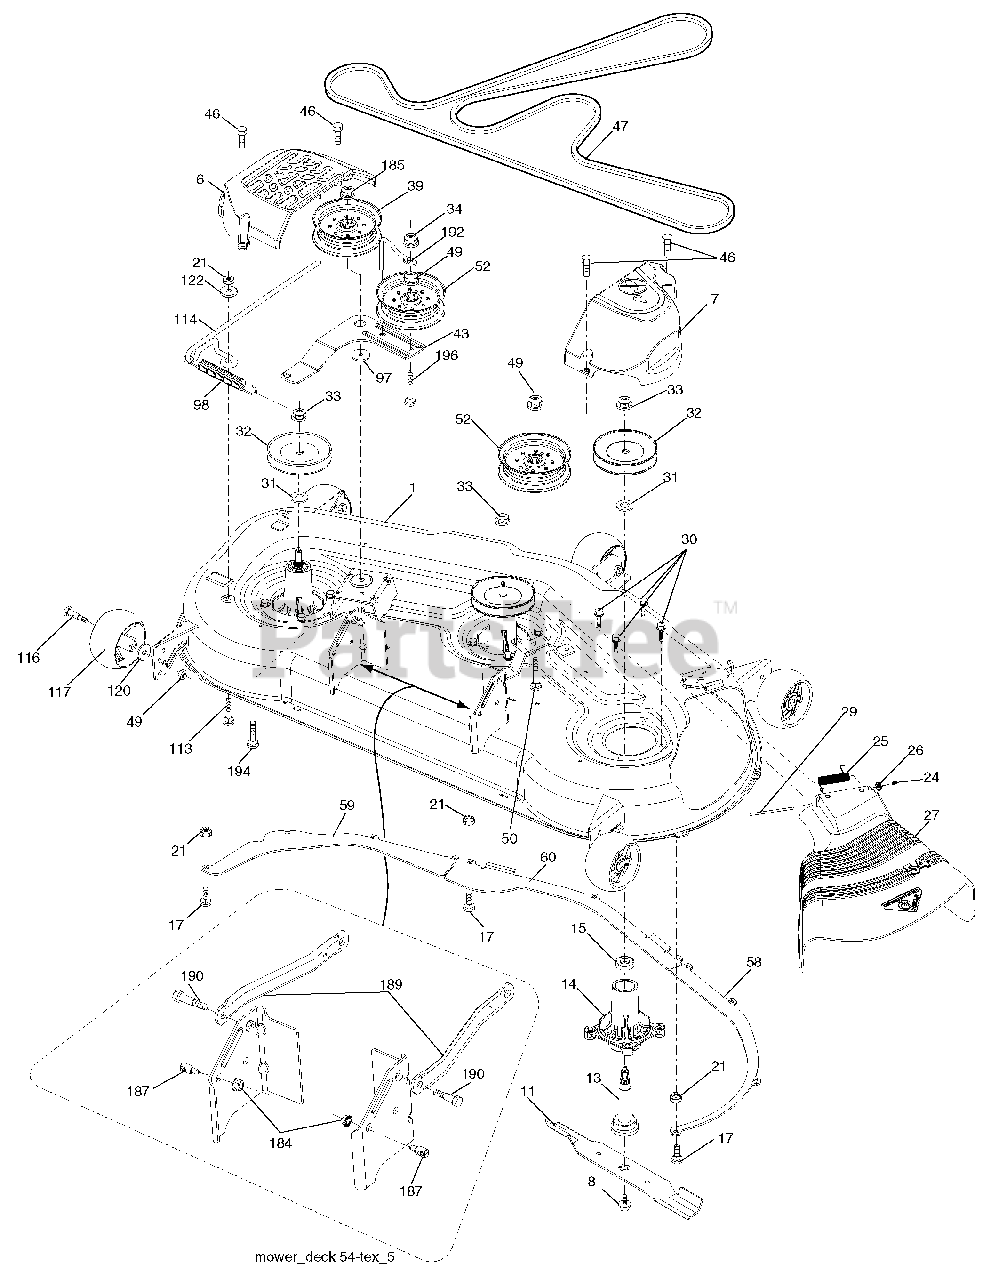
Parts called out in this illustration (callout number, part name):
1	Deck Weldment Mower
6	Cover Mandrel LH
7	Cover Mandrel RH
8	Bolt 7/16 Asm. Blade
8	Blade Mulching
11	Blade Bagging
13	Shaft Asm. w/Lower Bearing
14	Housing, Mandrel
15	Bearing, Ball, Mandrel
17	Bolt Carr. 5/16-18 x 5/8
21	Nut, Crownlock 5/16-18 unc
24	Cap Sleeve
25	Spring, Torsion
26	Nut, Push
27	Deflector Shield
29	Rod, Hinge
30	Screw, Thdroll Washer Head
31	Washer, Spacer Mower Vented
32	Pulley, Mandrel
33	Nut, Flg. Top Lock
34	Nut Crownlock 3/8-16 unc
39	Pulley, Idler, Stationary
43	Arm, Idler
46	Screw, Thdroll. 1/4-20 x 5/8
47	V-Belt, Mower
49	Nut, Lock Flg. 3/8-16 unc
50	Bolt RDHD SQNK 3/8-16 unc x 2
52	Pulley Idler Clutching
58	Baffle Right
59	Baffle Left
60	Baffle Center
97	Washer Hardened
98	Spring Drive
113	Bolt Rdhd Sqnk 5/16-18 x 3/4
114	Rod Tension Relief
116	Bolt, Shoulder
117	Gauge Wheel
120	Washer 13/32 x 1-1/4 x 12Ga.
122	Bushing Tension Relief
185	Nut Lock Flange 7/16-14 Gr. 5
187	Stud Fastener w/"D" Anti-Rotation
188	Nut Lock Hex Flange 5/16-18
189	Arm Susp. Mower Rear
190	Bolt Shoulder
192	Keeper Belt Idler
194	Bolt Carr Sqnk 3/8-16 x 2-1/4
196	Bolt RDHD 3/8-16 unc x 2-1/2 Gr.5
196	High Lift Blade
196	Mandrel Asm. Service
196	Replacement Mower, Complete
